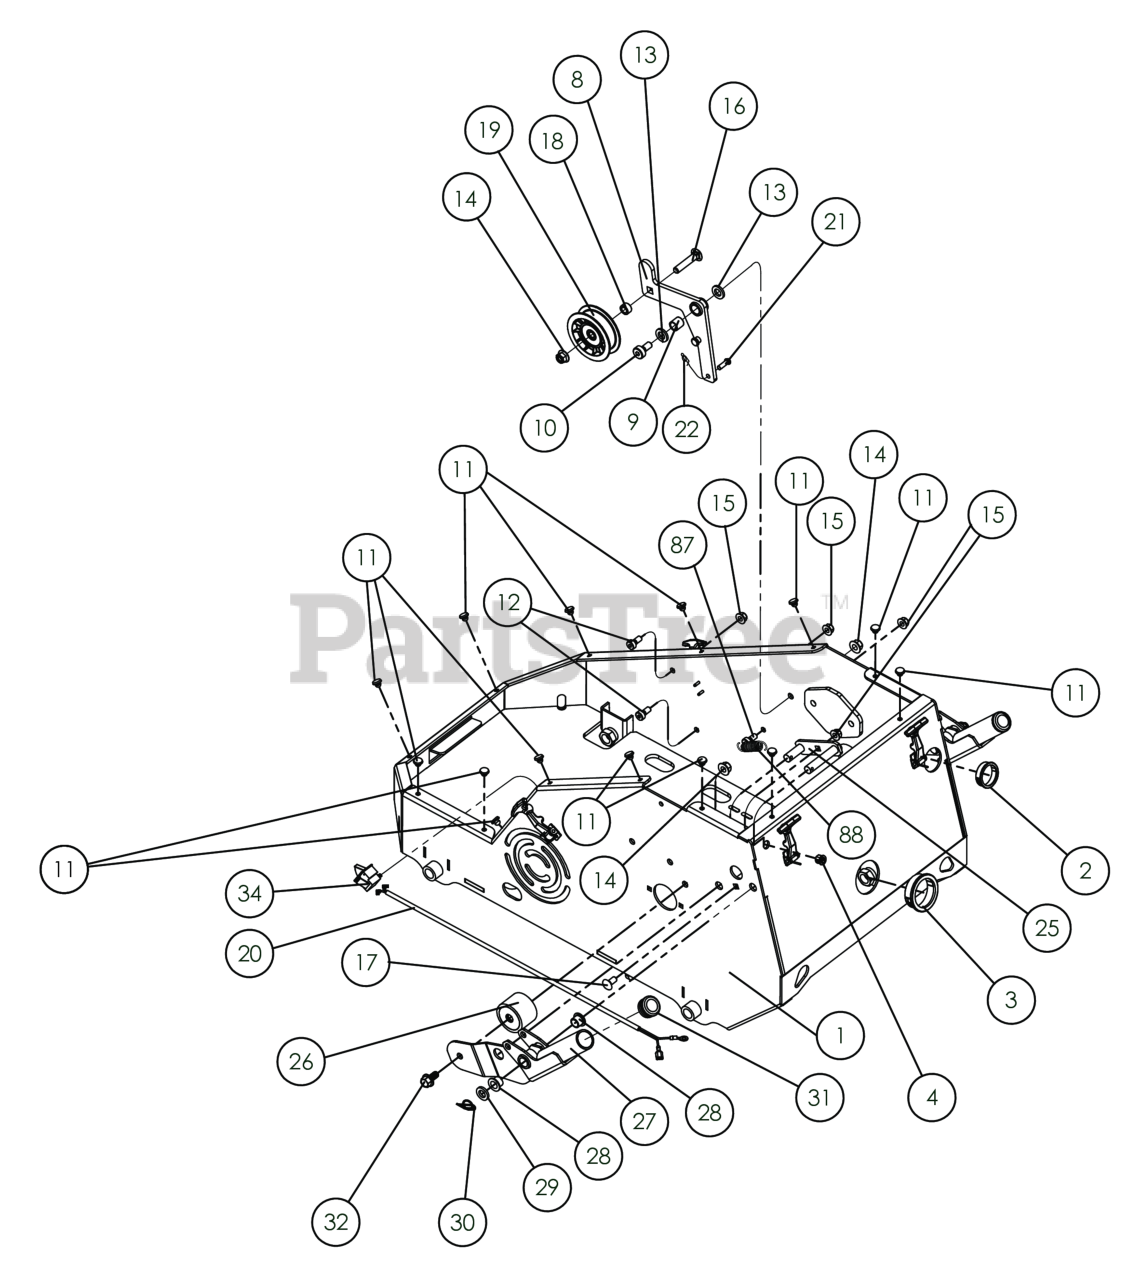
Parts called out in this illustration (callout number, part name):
1	WA, PL1801 FRAME BOELS W/DECALS
2	BUSHING, SNAP 1.31" ID
3	BUSHING, SNAP 1.81" ID
4	BUSHING, SPLIT 0.350" NYLON BLACK
8	WA, IDLER ARM PL18
9	BRG, SLEEVE Ø.500" X Ø.625" X .625"
10	BLT-SLDR,SH.500"X1.00",.375"-16X.63"G-8ZP
11	RUBBER BUMPER PUSH IN
12	BLT-SLDR,SH.375"X2.25",.313"-18X.50"G-8ZP
13	WSHR-NYL, FLT, .500" X .875" X .125"
14	NUT-HEX-NYLK, FLG .375"-16 ZP
15	NUT-HEX-NYLK, FLG .3125-18 ZP
16	BOLT CARRIAGE 3/8"-16 X 2" ZP
17	BOLT CARRIAGE 5/16"-18 X 3/4" ZP
18	TUBE SPACER 0.625" OD X 0.357" LONG
19	PULLEY IDLER 2.75" OD X 3/8" BORE
20	WIRE HARNESS PL HOOD SWITCH
21	CLEVIS PIN, 1/4 X 3/4
22	1/4" RUE RING
25	WA, ISO MOUNT
26	ISOLATOR, VIBRATION HANDLE SC181H
27	WA, REVOLVER LH BOELS SERVICE
28	BUSHING .500" ID
29	WSHR-STL,FLT .500"X.875"X.134" MAB ZP
30	RING, RUE .500"
31	PLUG TUBE INSERT 1.25" O.D.
32	SER HEX WASHER 3/8" - 16
34	SWITCH INTERLOCK
87	BOLT SHOULDER 3/8 X 1"
88	SPRING IDLER UPPER OS900SP
